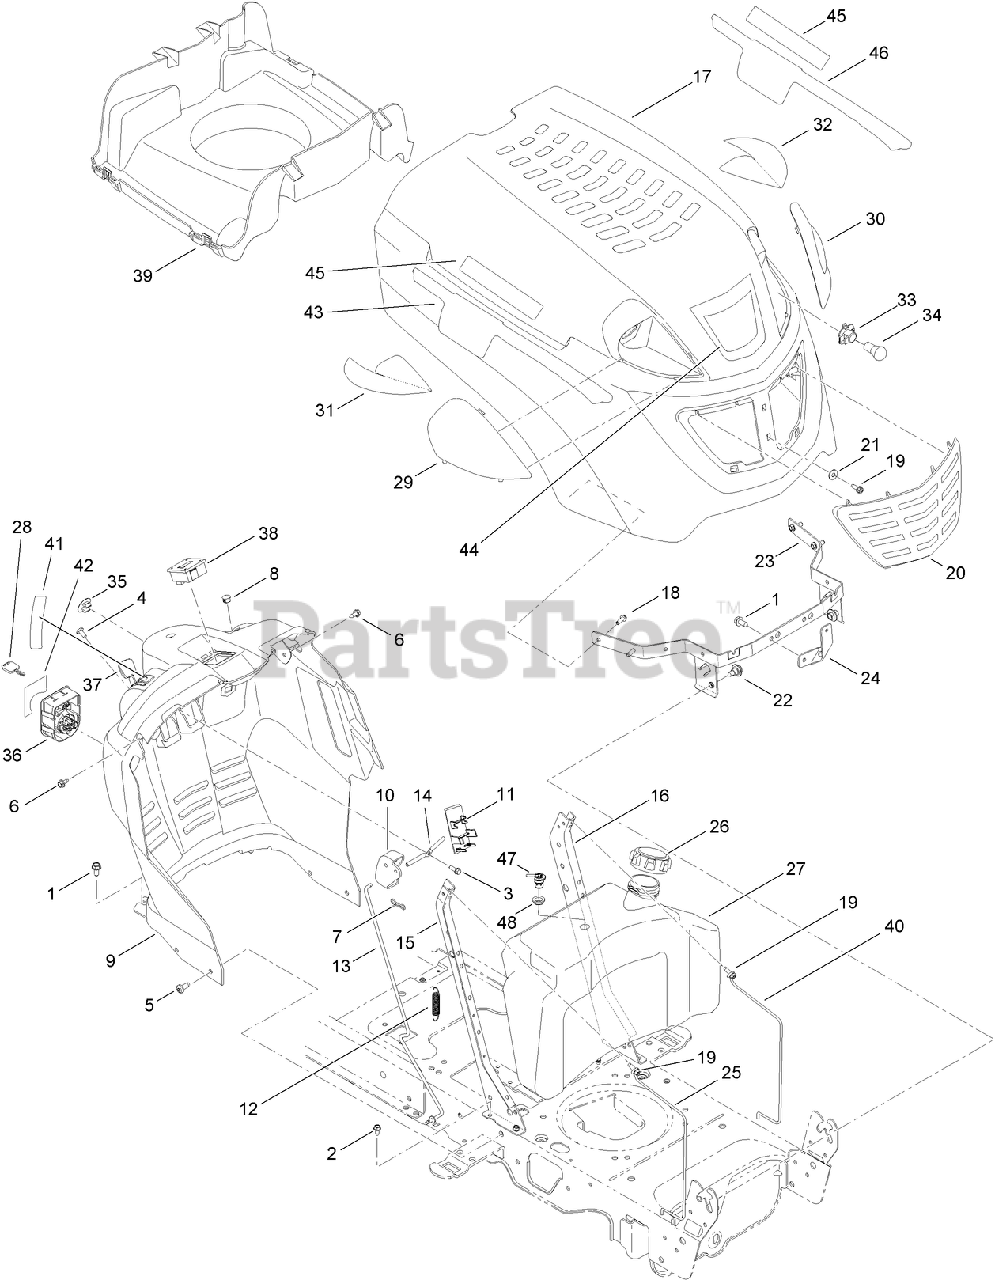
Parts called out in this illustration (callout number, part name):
1	SCREW-TAP
2	SCREW-HWHTF
3	SCREW-TAP
4	SCREW-TAP
5	SCREW-TAP
6	SCREW-HWH
7	PIN-COTTER
8	CAP-PLUG, HOLE
9	DASH-MANUAL, PTO
10	LEVER-DASH
11	COVER-CRUISE
12	SPRING-EXTENSION
13	ROD-LATCH
14	ROD-LEVER, BENT
15	SUPPORT-DASH, PLATE (RH)
16	SUPPORT-DASH, PLATE (LH)
19	SCREW-TAP
21	WASHER-FLAT
22	BOLT-SHOULDER, TAP
23	BRACKET-PIVOT
24	BRACKET-SUPPORT, HOOD
25	ROD-SUPPORT
26	CAP-FUEL
27	TANK-FUEL
28	KEY-IGNITION
29	LENS-RH
30	LENS-LH
31	REFLECTOR-RH
32	REFLECTOR-LH
33	SOCKET-HEADLIGHT
34	LAMP-12V, MINIATURE
35	PLUG-CHOKE
36	MODULE-SWITCH, IGNITION
37	CABLE-THROTTLE/CHOKE
38	METER-HOUR
39	PLENIUM-HOOD
40	ROD-SUPPORT, LH TANK
41	DECAL-THROTTLE
43	DECAL-HOOD, RIGHT SIDE
44	DECAL-HOOD
46	DECAL-HOOD, LEFT SIDE
47	VALVE, ROLLOVER GROMMET
48	GROMMET, RUBBER, 23.0 ID
